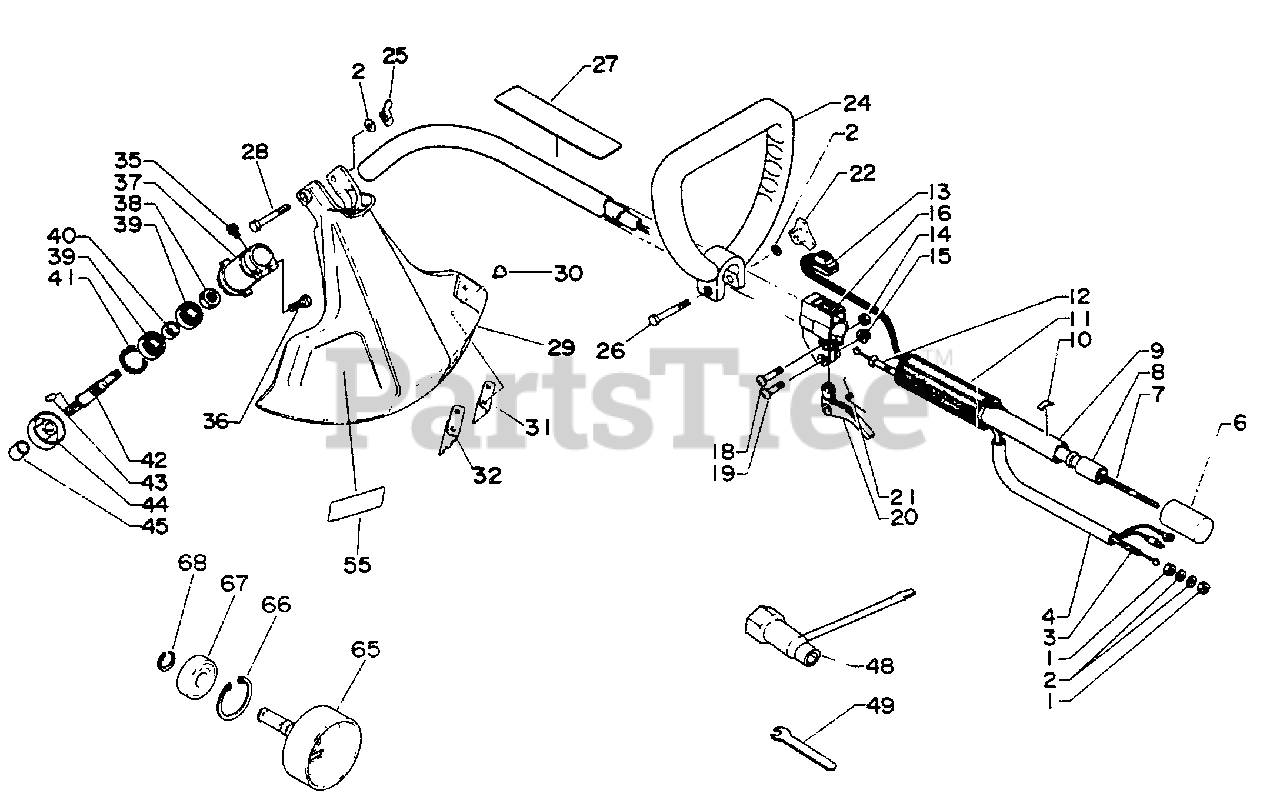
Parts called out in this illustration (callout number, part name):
2	WASHER 6.5×11.5×0.8
3	CABLE, THROTTLE
6	LABEL - GENERATOR
7	DRIVESHAFT - FLEXIBLE
8	BUSHING
9	PIPE, MAIN
10	LABEL - ALIGNMENT
11	GRIP, HANDLE
12	GUIDE, CABLE
13	IGNITION SWITCH ASSY
14	NUT M5
15	LOCKNUT - 5
16	BRACKET, THROTTLE
18	SCREW 5×28
20	TRIGGER, THROTTLE
21	SPRING, THROTTLE
22	KNOB, FASTENER
24	HANDLE
25	NUT, WING 6
26	BOLT - 6×40
27	LABEL - CAUTION
28	BOLT - 6×50
29	SHIELD
30	SCREW 5×16
31	KNIFE, TRIMMER LINE
32	PROTECTOR
35	SCREW 4×10
36	BOLT - 5×25
37	CASE, GEAR
38	NUT 12 L.H.
39	BEARING, BALL 6001 DDU
41	RING, SNAP 28
42	SHAFT, GEAR
44	PLATE, ADAPTER - UPPER
45	LABEL - GENERATOR
48	WRENCH 8×19, W/S. DRIVER
55	LABEL, ECHO
65	DRUM, CLUTCH
66	RING, SNAP Ø32
67	BEARING, BALL 6201
68	RING, RETAINING - 12
